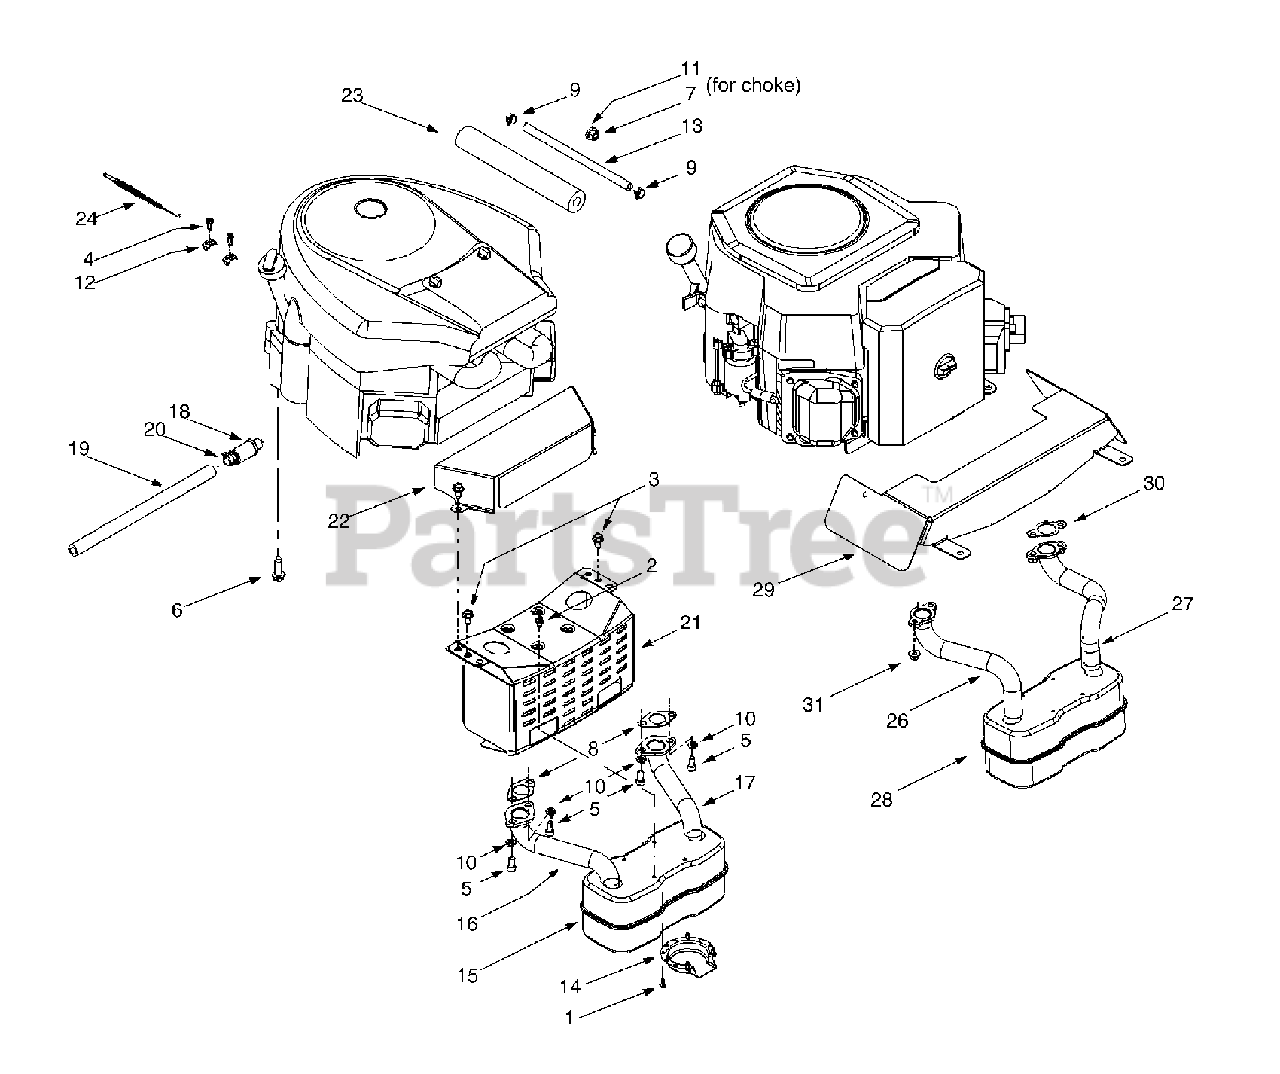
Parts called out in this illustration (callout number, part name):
1	Self-tapping Screw, #8-18 x .5
2	Self-tapping Screw, 1/4-20 x .5
3	Self-tapping Screw, 5/16-18 x .625
4	Screw, #10-32 x .625
5	Socket Cap Screw, 5/16-18 x .625
6	Self-tapping Screw, 3/8-16 x 1.25
7	Hex Nut, 3/8-16
8	Exhaust Gasket
9	Hose Clamp
10	Lock Washer, 5/16
11	Flat Washer
12	Casing Clamp
13	Fuel Line Hose
14	Muffler Deflector
15	Muffler, Twin Inlet
16	RH Exhaust Pipe
17	LH Exhaust Pipe
18	Oil Drain Valve
19	Oil Drain Hose
20	Oil Drain Cap
22	Engine Heat Shield
23	Foam (fits over fuel line)
24	Throttle Cable (Model R814K)
26	RH Exhaust Pipe (Model W814H)
27	LH Exhaust Pipe (Model W814H)
28	Muffler, Twin Inlet (Model W814H)
29	Engine Heat Shield (Model W814H)
30	Exhaust Gasket (Model W814H)
31	Flange Nut, M8 x 1.25-6 (Model W814H)
